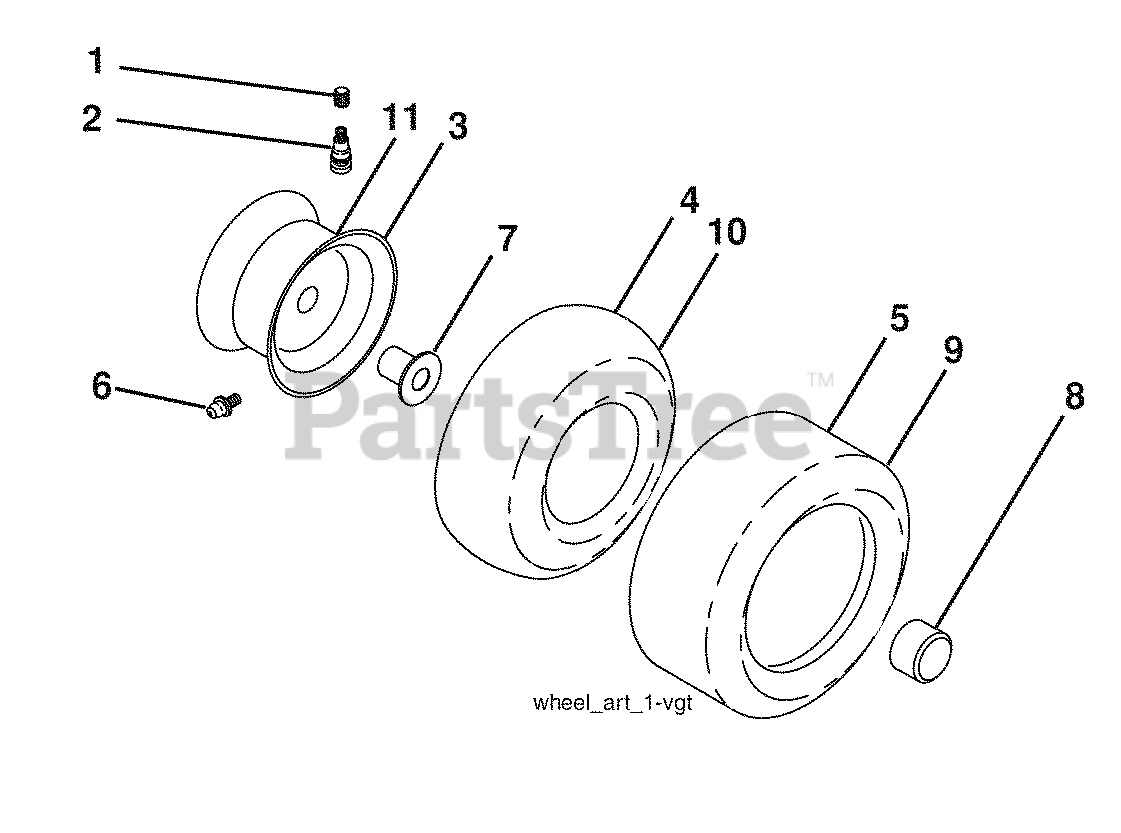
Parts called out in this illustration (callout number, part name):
2	VALVE STEM LT
3	RIM ASSEMBLY, FRONT
4	TUBE.16X6.5/7.5-8
5	TIRE HEAVY DUTY
6	FITTING LT
7	BEARING T
8	CAP, AXLE BLK
9	TIRE.TS.20X10-8
10	TUBE
11	RIM ASM 8" REAR SILVER
